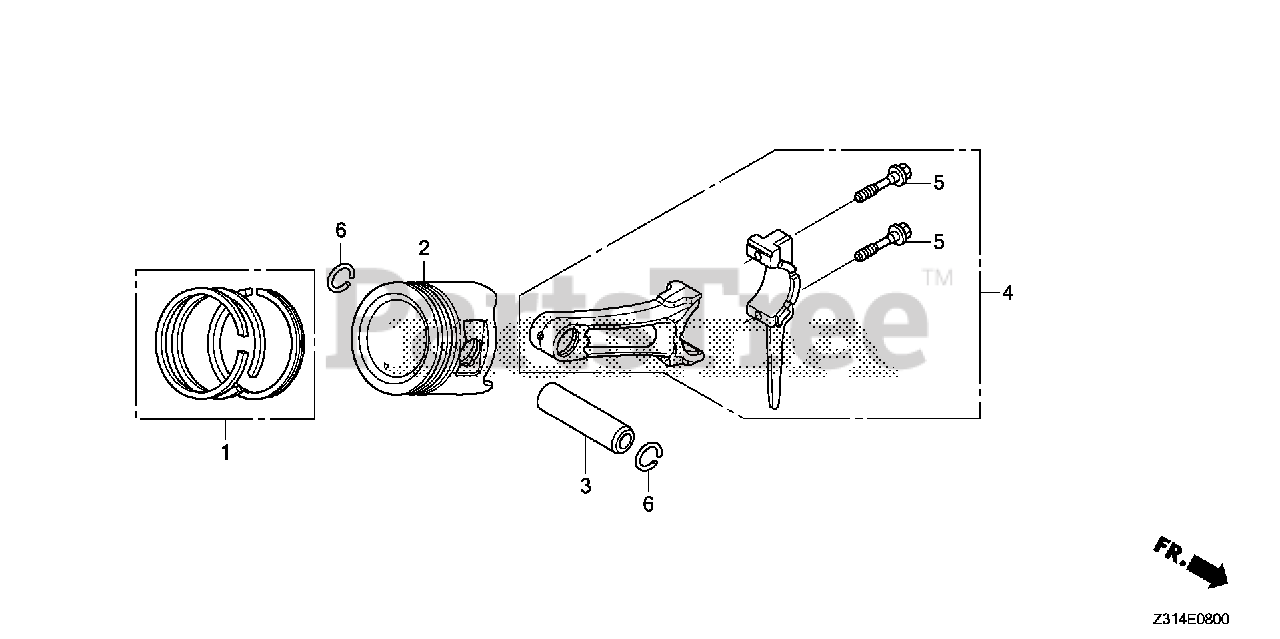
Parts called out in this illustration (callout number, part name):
1	RING SET, PISTON (STD) (TEIKOKU)
1	RING SET, PISTON (0.25) (TEIKOKU)
1	RING SET, PISTON (0.50) (TEIKOKU)
1	RING SET, PISTON (0.75) (TEIKOKU)
2	PISTON (STD)
2	PISTON (0.25)
2	PISTON (0.50)
2	PISTON (0.75)
3	PIN, PISTON
4	ROD ASSY., CONNECTING (0.25 LOWER SIZE)
4	ROD ASSY., CONNECTING (STD)
5	BOLT, CONNECTING ROD
6	CLIP, PISTON PIN (20MM)
